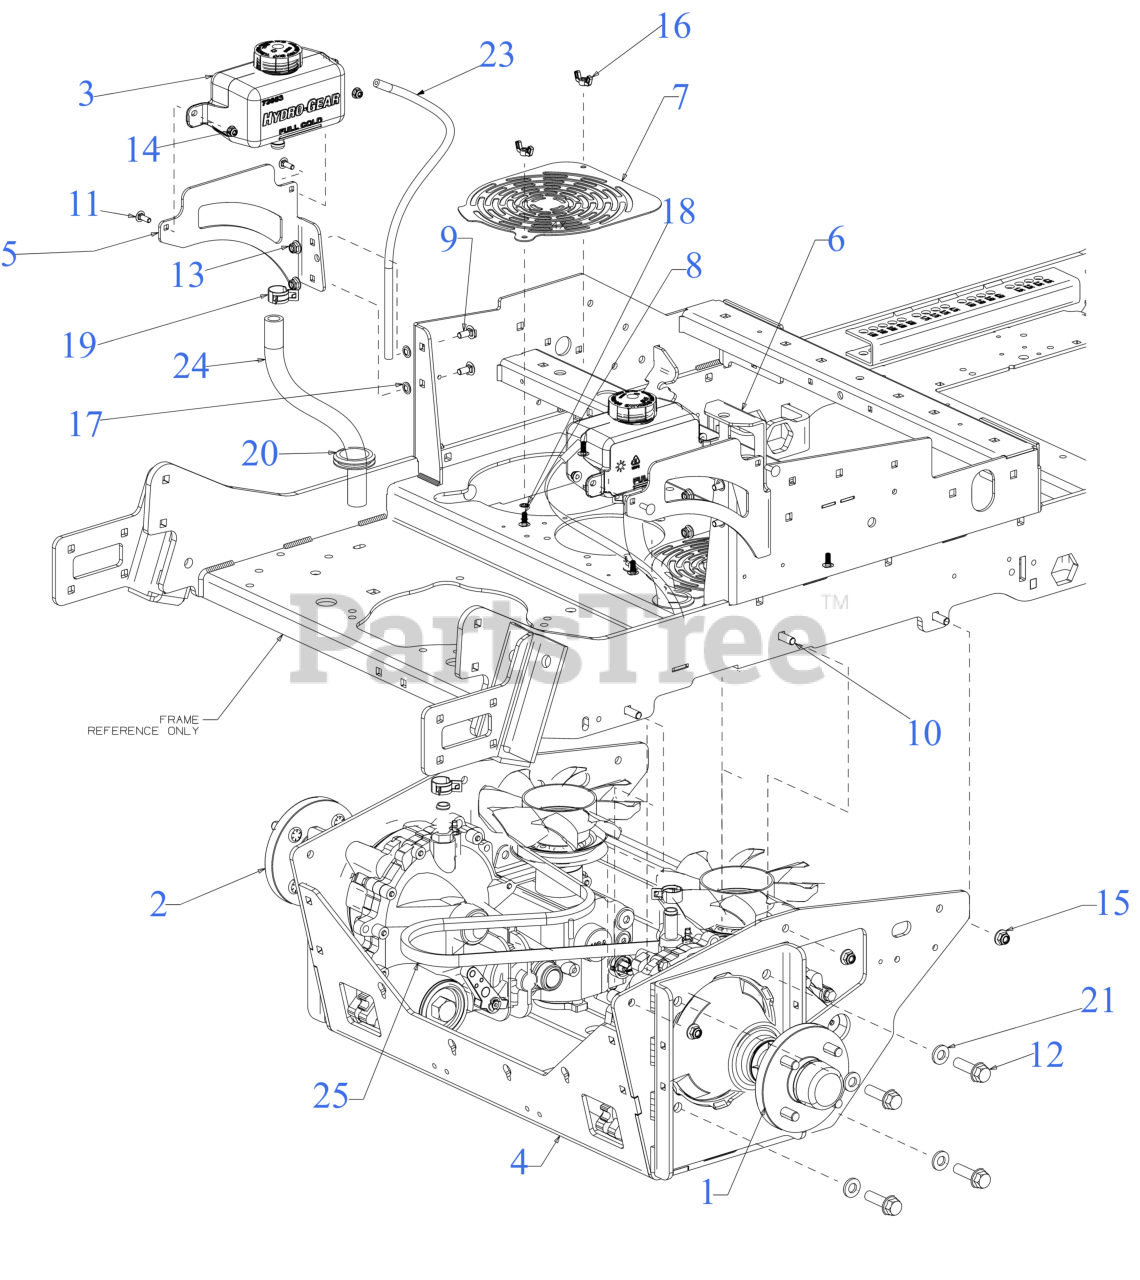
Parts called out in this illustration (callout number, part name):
1	HYDRO TRANSMISSION (RH) (W/RTN)
2	HYDRO TRANSMISSION (LH) (W/RTN)
3	1L EXPANSION TANK
3	CAP-EXPANSION TANK
4	SUB FRAME BRACKET
5	TANK MOUNT BRACKET (LH)
6	TANK MOUNT BRAKET (RH)
7	TRANSMISSION COVER PLATE
8	CARRIAGE BOLT 1/4-20 x .62
9	CARRIAGE BOLT 5/16-18 x .75
10	CARRIAGE BOLT 3/8-16 X1.25 GR5
11	SCREW 1/4-20 x .75 GR5
12	FLANGE BOLT 1/2-13:1.75:GR5
13	FLANGE LOCK NUT 5/16-18
14	FLANGE LOCK NUT
16	WING NUT 1/4-20
18	RETAINER-BOLT .25ID x .50OD
19	HOSE CLAMP
20	RUBBER GROMMET (1.50X2.13X.563)
21	FLAT WASHER .510 x 1.000 x .125
23	VENT HOSE 3/16 ID 51"LG
24	OIL HOSE 5/8 ID X 12.5 LG
25	V-BELT 66.34"
